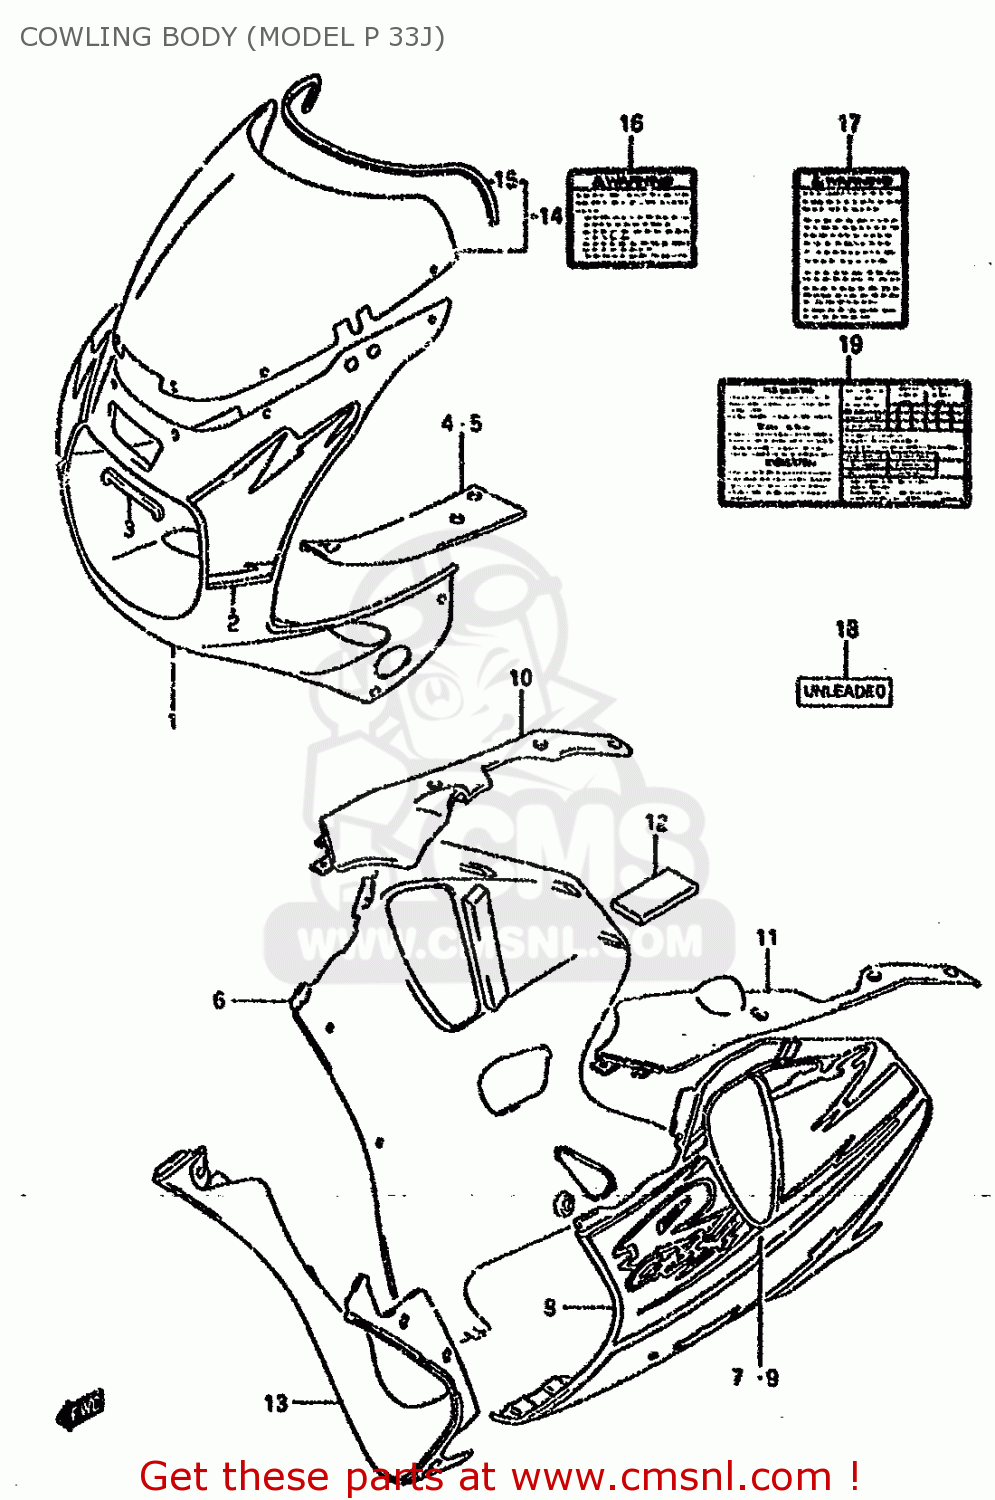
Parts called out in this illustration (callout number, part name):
1	COWLING ASSEMBLY,BODY
2	TAPE SET,COWLING BODY,FRONT
3	CUSHION,FR POSITION LAMP
4	PANEL,UPR,R
5	PANEL,UPR,L
6	COWLING ASSY,UNDER,R
7	TAPE SET,COWL UNDER,R
8	COWLING ASSY,UNDER,L
9	TAPE SET,COWLING,UNDER
10	PANEL,LWR,R
11	PANEL,LWR,L
12	CUSHION,PANEL
13	COWLING,UNDER CTR
14	WINDSCREEN SET
15	MOLDING
16	LABEL, WARNING SAFETY
17	LABEL (WARNING SCREEN)
18	LABEL,CAUTION
19	LABEL,TIRE AIR PRESSURE
